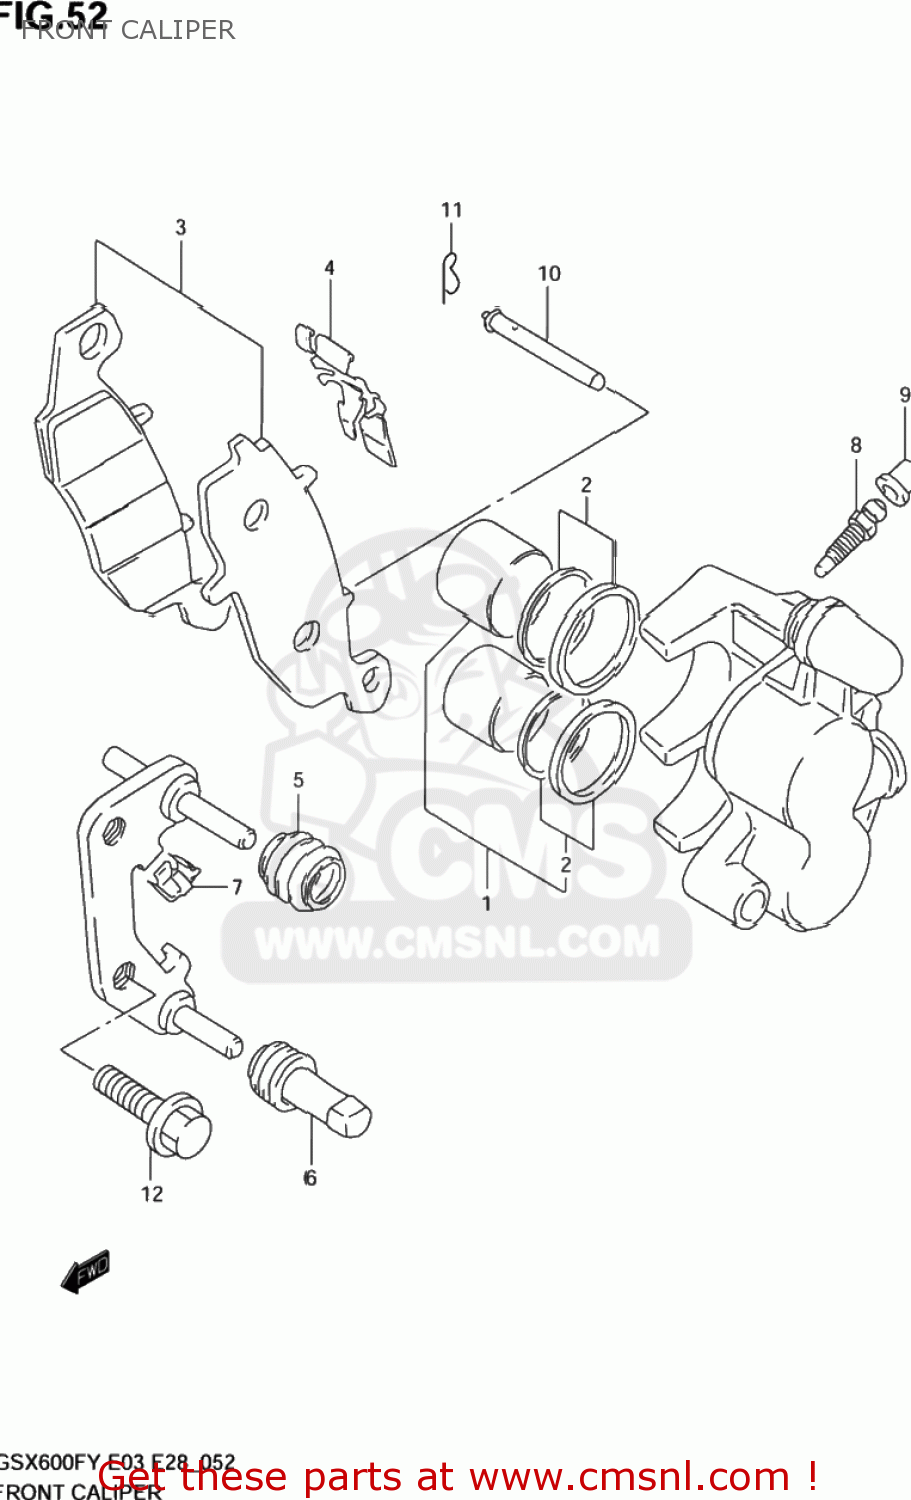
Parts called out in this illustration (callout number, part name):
1	PISTON SET
2	SEAL SET,PISTO
3	PAD SET,R (NAS)
4	SPRING,PAD,R
5	BOOT,AXLE
6	INSULATOR,AXLE
7	GUIDE,PAD
8	BLEEDER
9	CAP,BLEEDER PLUG
10	PIN,PAD
11	CLIP,PAD PIN
12	BOLT
